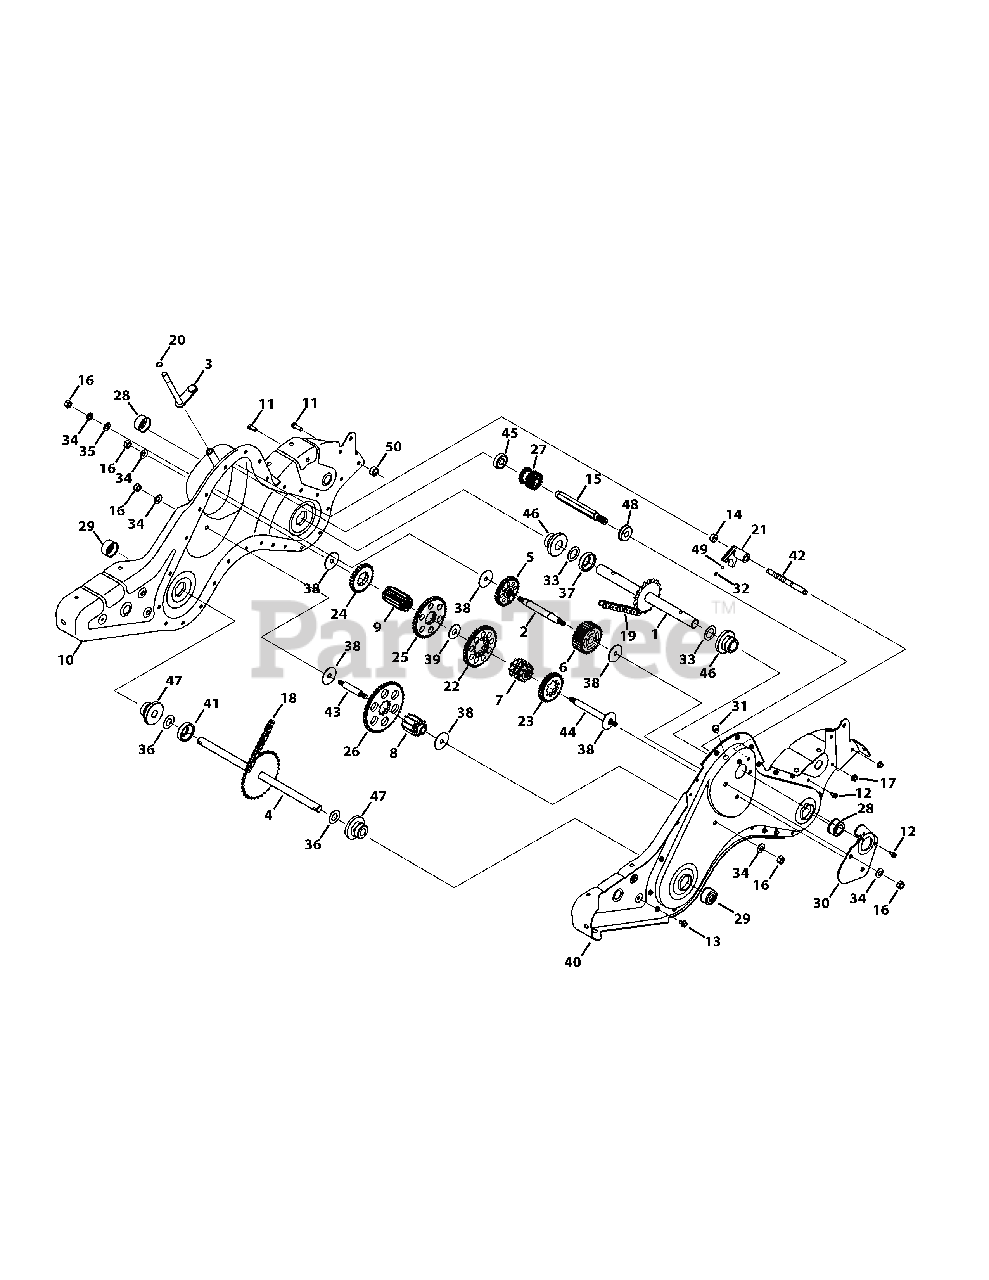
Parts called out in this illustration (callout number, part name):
1	Tine Shaft Assembly
2	Jack Shaft Assembly
3	Shif Input Shaft Assembly
4	Wheel Shaft Assembly, 33T
5	Reverse Idler Gear Assembly, 30T
6	Tine Idler Gear Assembly, 30T
7	Tine Input Sprocket Assembly, 9T
8	Wheel Input Sprocket Assembly, 10T
9	Gear Assembly, 11T
10	RH Chain Case Housing
11	Hex Head Screw, 5/16-18 x 1.00
12	Hex Washer Screw, 1/4-20 x .625
13	Hex Washer Screw, 5/16-18 x .750
14	Spacer, .505 x .88 x .440
15	Input Shaft, .75
16	Hex Nut, 7/16-20
17	Flange Lock Nut, 5/16-18
18	Endless Chain, #420 x 50
19	Endless Chain, #50 x 54
20	Snap Ring, .500
21	Clutch Collar
22	Gear Spur, 44T
23	Gear Spur, 30T
24	Gear Spur, 30T
25	Gear Spur, 44T
26	Gear Spur, 44T
27	Gear Spur, 16T
28	Shaft Seal, 1.0
29	Shaft Seal, .75
30	Positioner Gear Bracket
31	Tapered Cap Plug
32	Compression Spring, .230
33	Flat Washer, 1.03 x 1.62 x .03
34	Lock Washer, 7/16
35	Flat Washer,.474 x .879 x .064
36	Washer, .760 x 1.500 x .020
37	Spacer, 1.0 x 2.0 x .5
38	Thrust Washer, .445 x 1.920 x .040
39	Flat Washer, 1.595 x .635 x .062
40	LH Chain Case Housing
41	Spacer, .75 x 2.0 x .50
42	Shaft Detent, .5 DIA
43	Jack Shaft, .625 x 2.385
44	Jack Shaft, .6250 x 5.0050
45	Ball Bearing, 17 x 40 x 12
46	Flange Bearing, 1.0 x 2.5 x 1.38
47	Flange Bearing, .75 x 2.5 x 1.38
48	Ball Bearing, 17 x 40 x 12:6203
49	Detent Ball, .250
50	Spacer, .315 x .750 x .375
